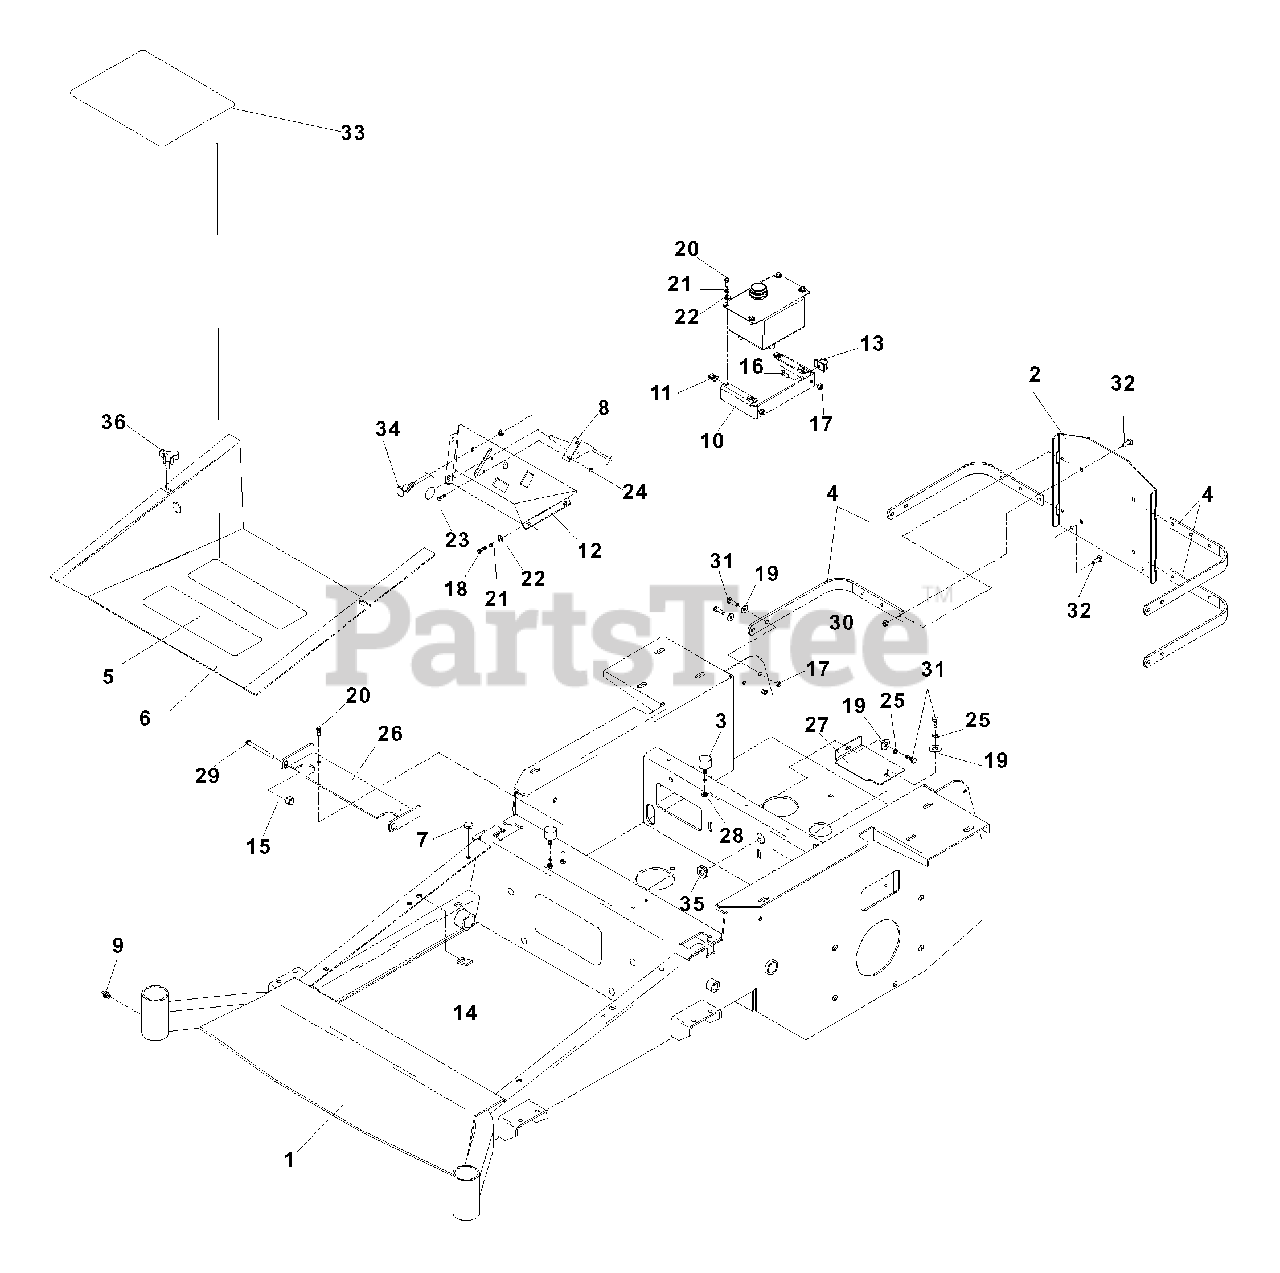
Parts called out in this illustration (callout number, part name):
1	FRAME/DECALS, 52"/61"
1	FRAME/DECALS, 72"
3	STUD/PLATE MOUNT
5	ANTI-SKID PAD
6	FOOT PLATE
8	THROTTLE CABLE
9	ZERK, DRIVE IN
10	TANK MOUNT
11	"U" TYPE, 1/4C, RETAINER
12	CONSOLE W/DECAL
13	PUSH MOUNT WIRE CLIP
14	"U" CLIP, 5/16 C
15	NUT, 3/8C, NYLOC
16	HCS, 5/16 C x 3/4
17	NUT, 5/16 C, NYLOC
18	TFS, 1/4C x 5/8
19	WASHER, 5/16
20	HCS, 1/4C x 3/4
21	LOCKWASHER, 1/4
22	WASHER, 1/4
23	HCS, #10-24 x 1/2
24	NUT, #10-24, NYLOC
25	LOCKWASHER, 5/16
26	SEAT BRACKET
27	IDLER COVER
28	NUT, 1/4C, NYLOC
29	HCS, 3/8 C x 2 3/4
30	NUT, 5/16C, CENTERLOCK
31	HCS, 5/16C x 1
32	RHSSNB, 5/16 C x 3/4
33	FLOOR PAN PAD MODELS 968999309,968999311, 968999314 ONLY
34	CHOKE CONTROL, NOT USED ON EFI MODELS
36	KNOB W/STUD
